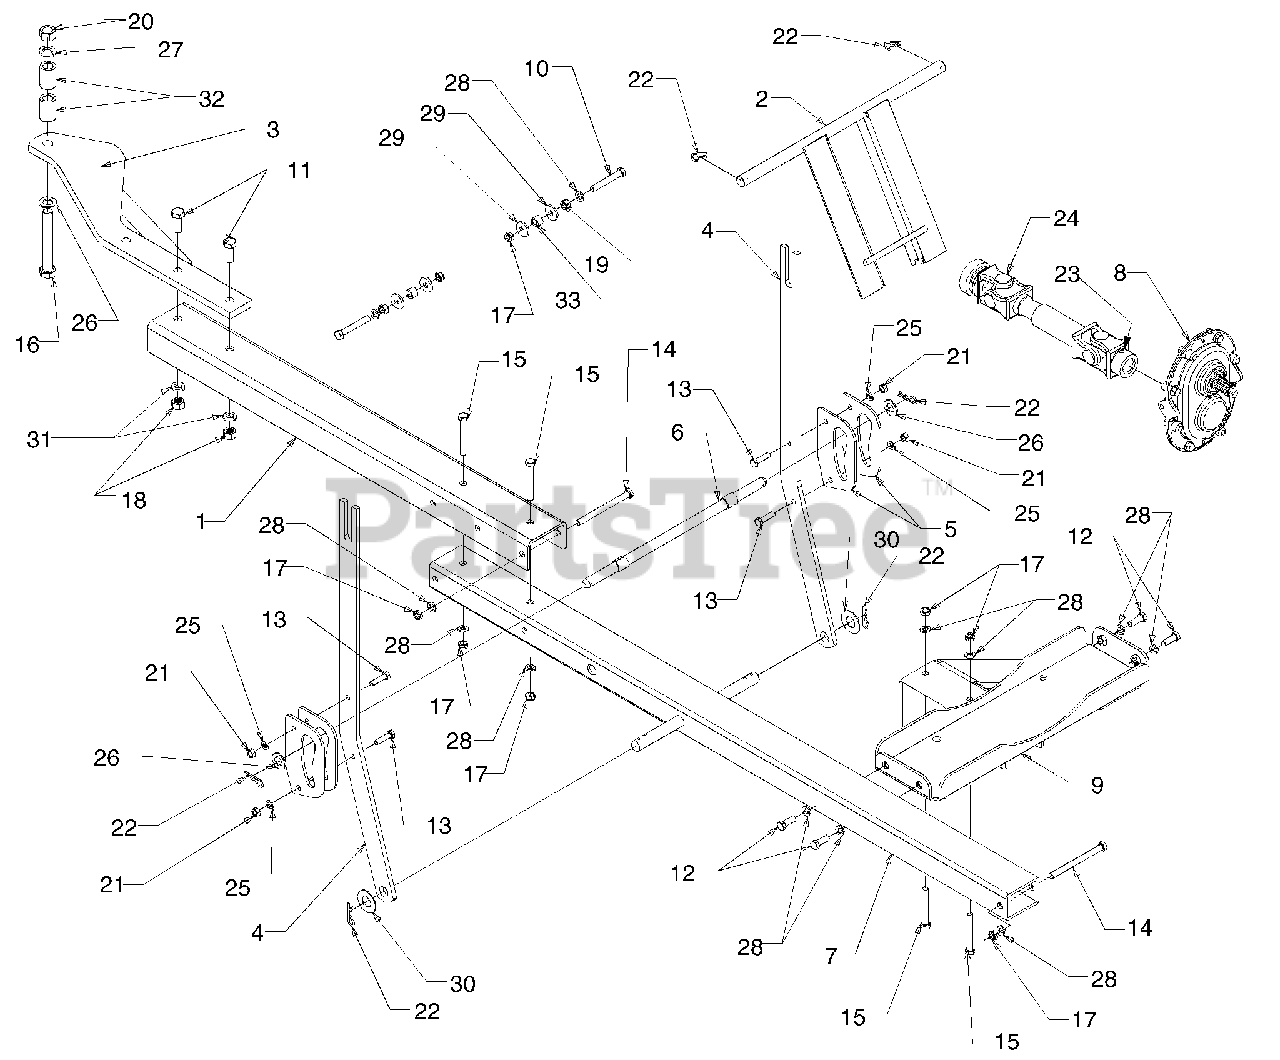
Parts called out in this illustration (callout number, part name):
3	HITCH HANGING BAR
9	BRKT ASM:HSG:MT
10	SCREW-HEX 3/8-24X2
11	SCREW-HEX 1/2-13 X
12	SCREW-HEX 3/8-16 X
13	SCREW-HEX 5/16-18
14	SCREW-HEX HD 3/8 2
15	SCREW-HEX 3/8-24 X
16	BOLT-HEX 5/8-18
17	NUT-HEX INS
18	NUT-HEX 1/2-13
19	NUT-HEX 3/8-24
20	NUT-HEX 5/8-18
21	NUT-HEX 5/16-18
22	HITCH PIN CLIP
23	PIN-SPRING SPIR 5/
24	SHF:DR:UNIV X 1344 LG
25	WASHER-LOCK 5/16
26	WASHER-FL-.635 ID
27	WASHER-LOCK 5/8
28	WASHER LOCK-3/8
29	WASHER-FL-.385 X 1
30	WASHER-FL
31	WASHER LOCK-1/2
32	HUB .635 ID X 1.00 OD X 1.50
33	SPACER-.375 X .625
